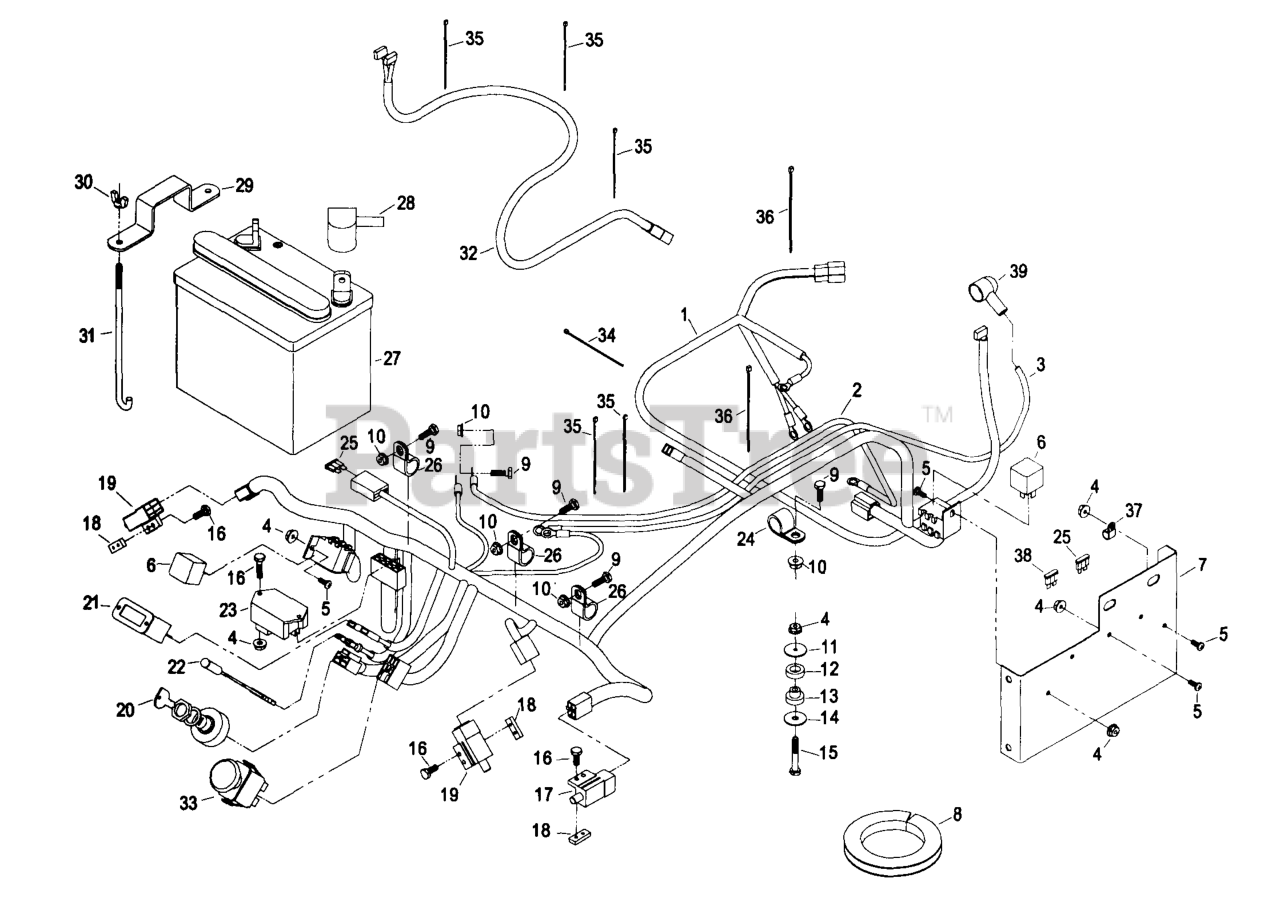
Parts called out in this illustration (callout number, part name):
1	HARNESS,WIRING 26KC EFI
2	WIRE-GROUND
7	PANEL-FUSES & RELAYS
12	RINGMOUNT-VIBRATION
13	MOUNT-BUSHING, VIBRATION
17	SWITCH-BRAKE
18	PLATE-TAPPED
20	SWITCH,IGNITION
21	METER-HOUR
22	INDICATOR-LED, RED
23	MODULE,INTERLOCK
24	CLIP-LOOM
25	FUSE-BLADE TYPE, 20 AMP
26	CLIP-LOOM
27	Battery-12v
29	STRAP-HOLDDOWN
30	WINGNUT
31	BOLT-HOLDDOWN
34	TIE-CABLE
35	TIE-PLASTIC
36	TIE-PLASTIC
37	CLIP-LOOM
39	INSULATOR-SOLENOID
